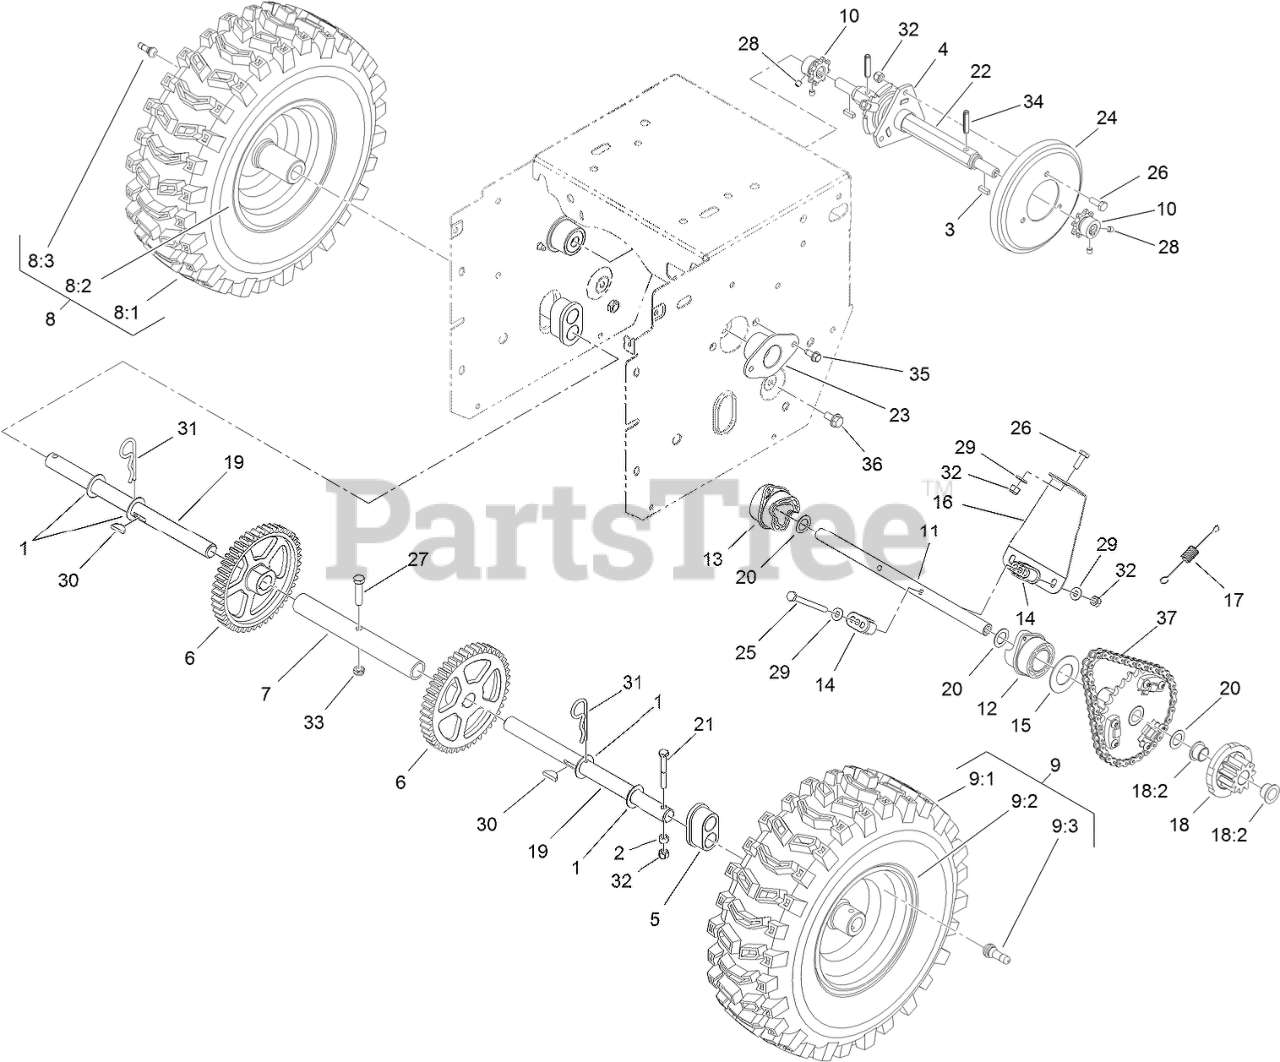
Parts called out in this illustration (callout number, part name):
1	WASHER-THRUST
2	SPACER-BLADE, ROTOR
3	KEY-SQUARE
4	TRUNNION-HEX
5	BEARING-AXLE
6	GEAR-AXLE, 44 TOOTH
7	TUBE-AXLE
8	RH WHEEL AND TIRE ASM
8:2	RIM-TIRE
8:3	STEM-VALVE
9	LH WHEEL AND TIRE ASM
9:2	RIM-TIRE
9:3	STEM-VALVE
10	SPROCKET-8 TOOTH
11	SHAFT-INTERMEDIATE
12	COLLAR-SHIFT, LH
13	COLLAR-SHIFT, RH
14	GUIDE-COLLAR
15	WASHER-THRUST
16	BRACE-COLLAR, SHIFT
17	SPRING-EXTENSION
18	11T GEAR ASM
18:2	BUSHING-FLANGE
19	SHAFT-AXLE
20	WASHER-FLAT
21	SCREW-HH
22	SHAFT-HEX
23	RETAINER-BEARING
24	WHEEL-FRICTION
25	SCREW-HH
26	SCREW-HH
27	SCREW-HH
28	SCREW-HSH
29	WASHER-FLAT
30	KEY-WOODRUFF
31	PIN-HAIR
32	NUT-LOCK, NI
33	NUT-LOCK, NI
34	PIN-ROLL, SLOTTED
35	SCREW-HWH
36	SCREW-HWHTF
37	CHAIN-ROLLER
37	LINK-CONNECTING
